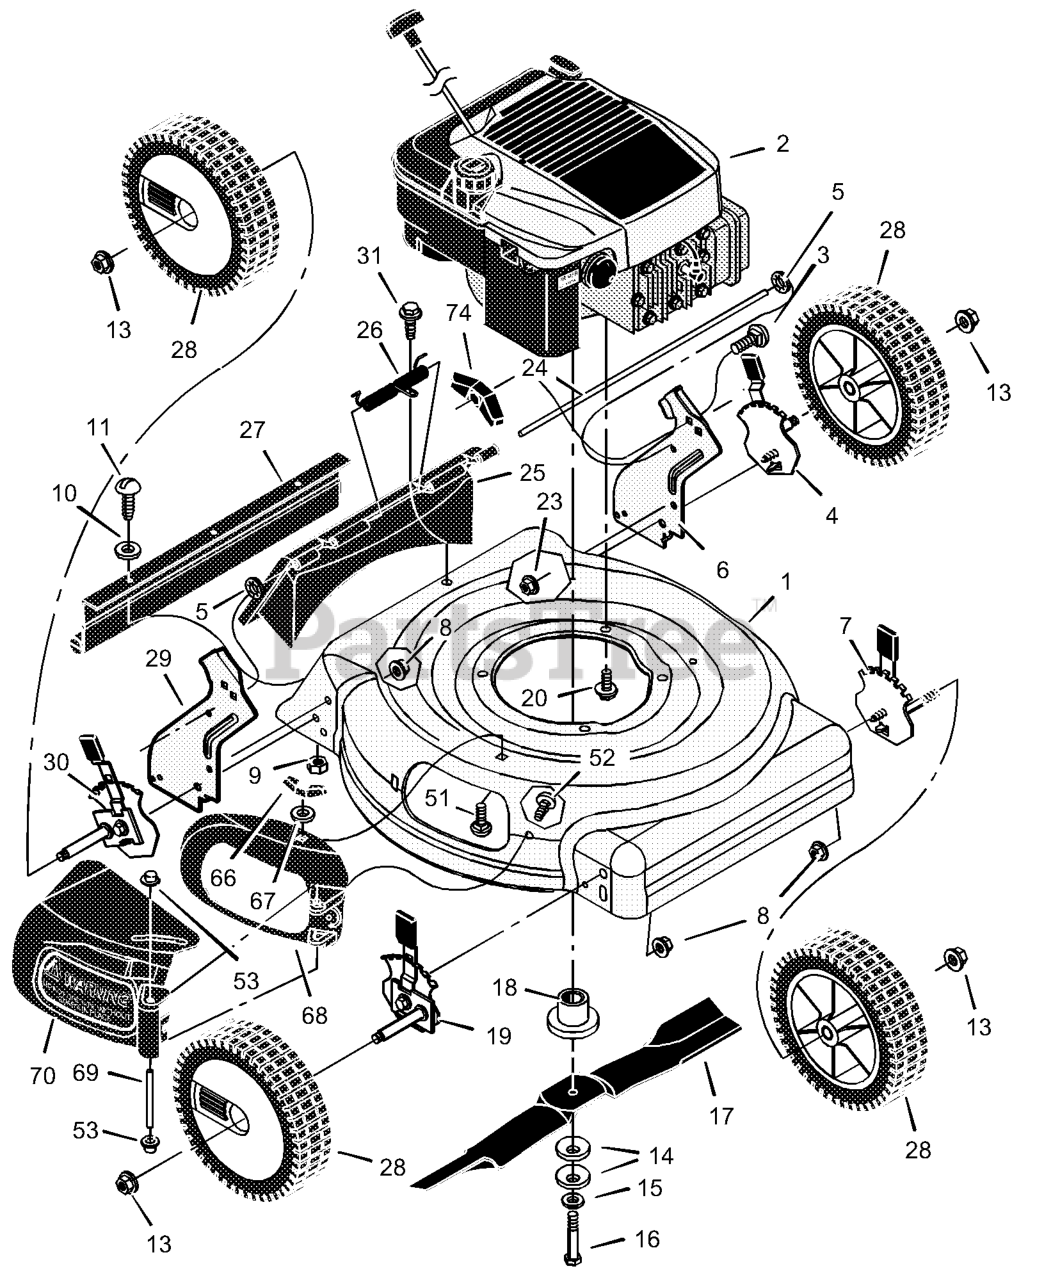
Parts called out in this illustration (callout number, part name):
1	Housing
2	Engine *
3	Bolt, Carriage
4	Adjuster, Left Rear Height
5	Push On Cap
6	Bracket, Left Handle
7	Adjuster, Left Front Height
8	Nut, Flange
9	Nut, Hex
11	Screw
13	Nut, Flange
14	Washer, Belleville
18	Adapter, Blade
19	Adjuster, Right Front Height
20	Bolt, Engine
23	Nut, Flange
24	Rod, Pivot
25	Door, Rear
26	Spring
27	Guard, Rear
28	Wheel
29	Bracket, Right Handle
30	Adjuster, Right Rear Height
51	Bolt, Carriage
53	Push On Cap
66	Wingnut
67	Retainer, Push
68	Bezel
69	Pin, Pivot
70	Deflector, Chute
